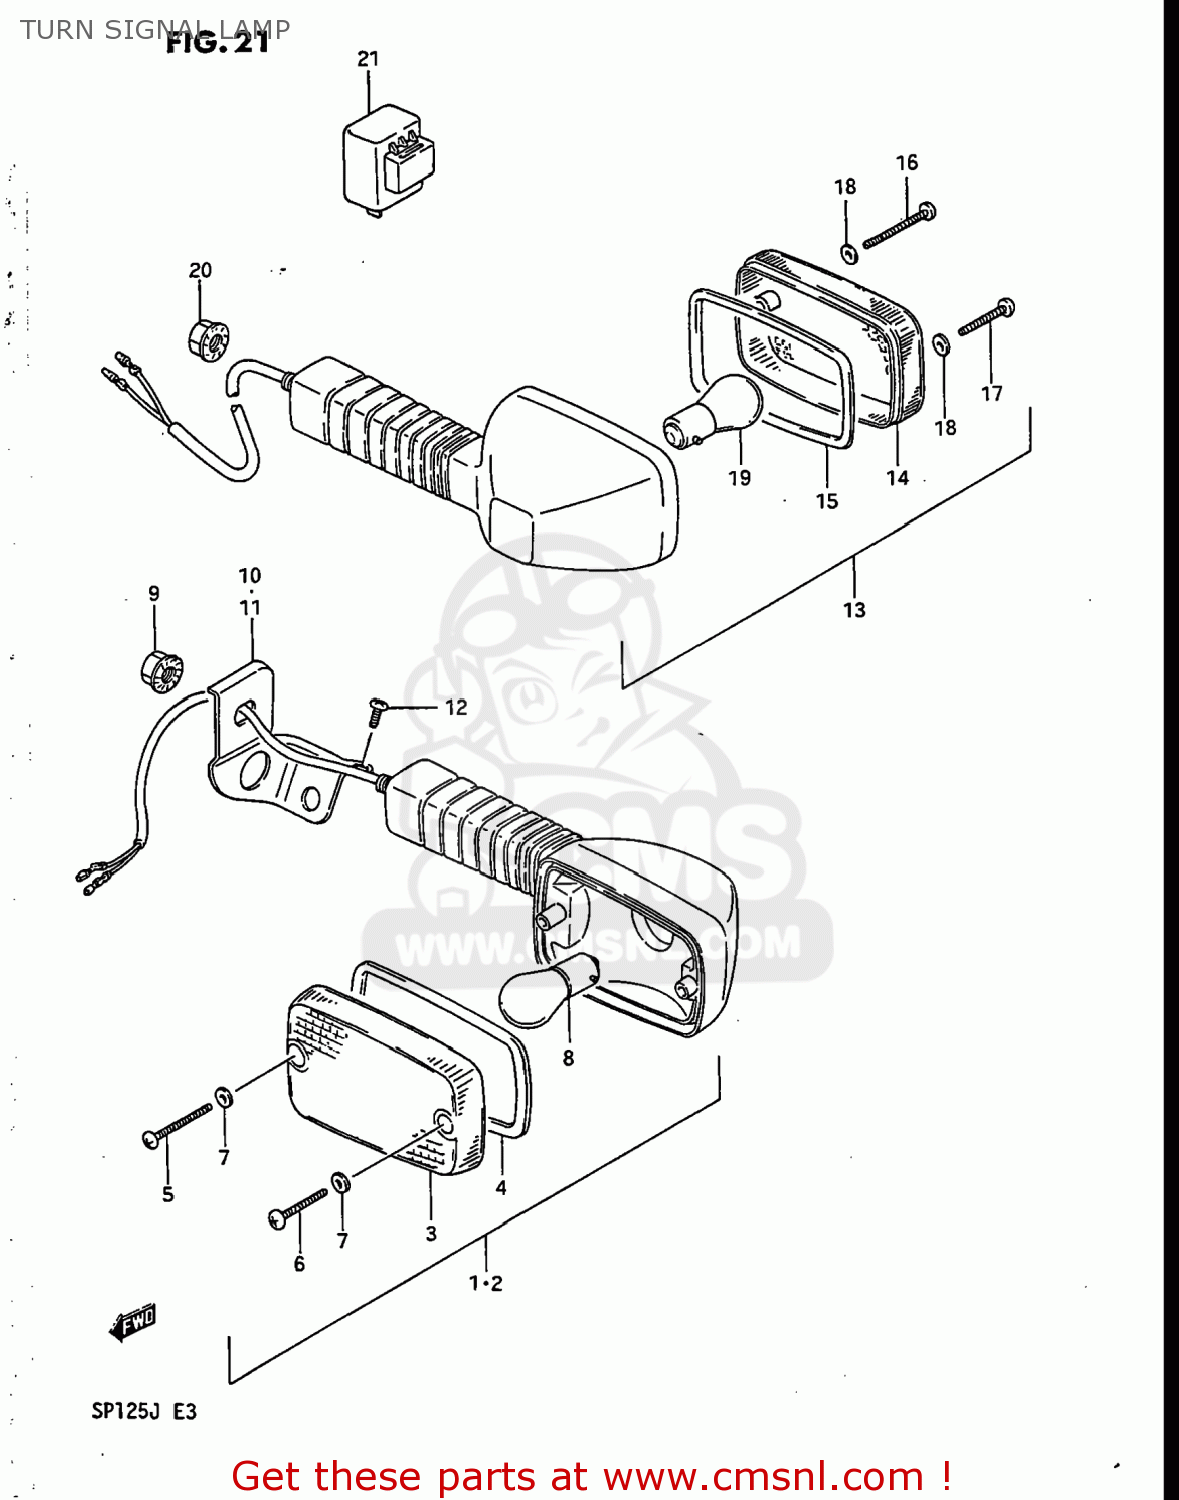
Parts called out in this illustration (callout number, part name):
1	LAMP ASSEMBLY,FRONT TURN SIGNAL
2	LAMP ASSEMBLY,FRONT TURN SIGNAL
3	LENS,FR
4	GASKET (NAS)
5	SCREW,TURN SIG LENS FITTING
6	SCREW
7	GASKET (NAS)
8	BULB(6V17W,STANLEY,A4513A)
9	NUT
10	BRACKET,FRONT TURN SIGNAL,RIGHT
11	BRACKET,FRONT TURN SIGNAL
12	SCREW
13	LAMP ASSY,RR TURNSIGNAL
14	LENS,FR
15	GASKET (NAS)
16	SCREW,TURN SIG LENS FITTING
17	SCREW
18	GASKET (NAS)
19	BULB(6V17W,STANLEY,A4513A)
20	NUT
21	RELAY,TURN SIGNAL
